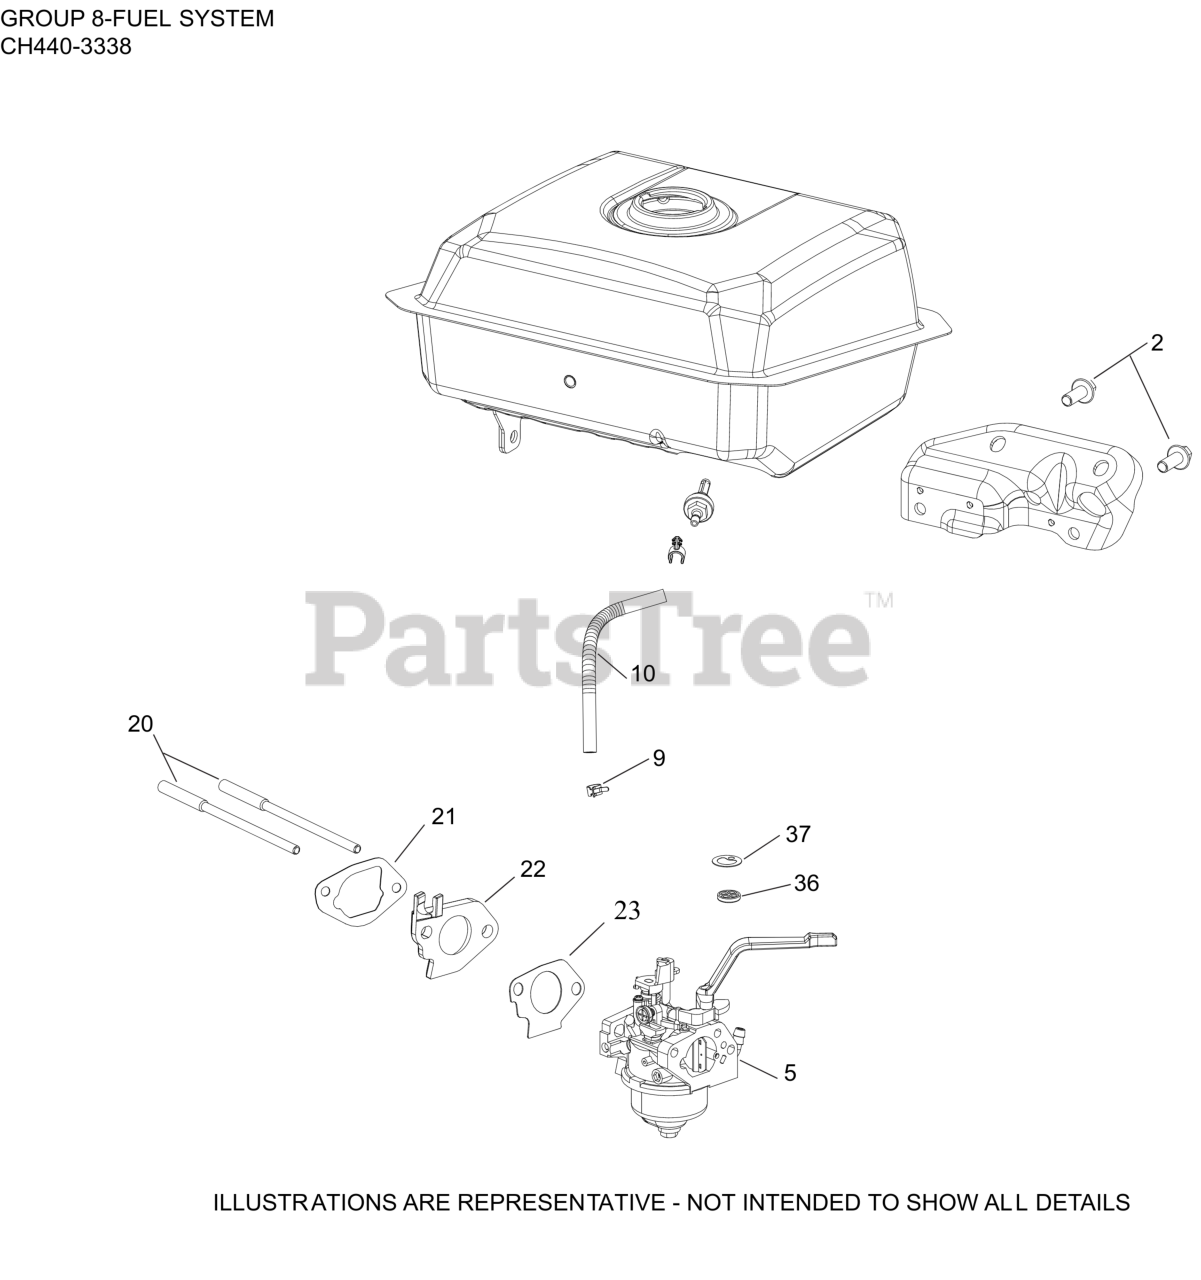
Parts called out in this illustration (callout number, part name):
2	SCREW, M8 X 20
5	CARBURETOR, ASSEMBLY
9	CLAMP, FUEL LINE
10	FUEL HOSE, LOW PERMEATION (310mm)
20	STUD, INTAKE
21	KIT, GASKET INTAKE
22	KIT, INSULATOR
23	GASKET, CARB TO INSULATOR
36	SEAL, INLET VALVE
37	KIT, FUEL SCREEN
NI	TOOL, SPARK PLUG WRENCH ASSY
NI	KIT, HIGH ALT (4000-8000 FT)
NI	KIT, HIGH ALT (8,000+ FT)
NI	KIT, CARBURETOR REPAIR
